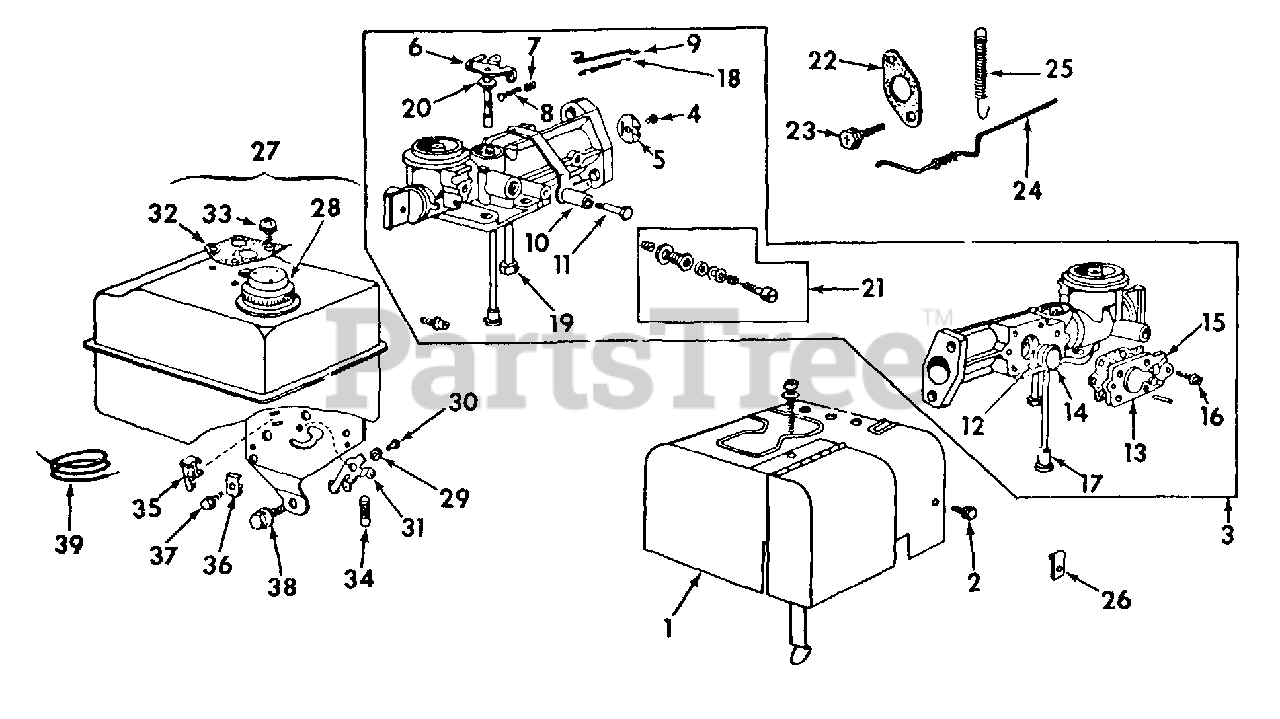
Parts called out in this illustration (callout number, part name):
2	SCREW, NO. 6 X 3/8 SHEET METAL
3	CARBURETOR ASSY
4	SCREW, THROTTLE VALVE
5	VALVE, THROTTLE
6	SHAFT LEVER ASSY, THROTTLE
7	SPRING, THROTTLE ADJUSTING
8	SCREW, THROTTLE ADJUSTING SPRING
9	LINK, THROTTLE
10	BELLCRANK
11	SCREW, SHOULDER
12	SPRING, FUEL PUMP DIAPHRAGM
13	DIAPHRAGM
14	CAP, SPRING
15	COVER, DIAPHRAGM
16	SCREW, DIAPHRAGM COVER
17	SCREEN, FUEL PIPE HOUSING
18	SPRING, THROTTLE LINK
19	FUEL PIPE ASSY
20	WASHER, THROTTLE SHAFT
21	KIT, NEEDLE VALVE
22	GASKET, CARBURETOR
23	SCREW, CARBURETOR MOUNTING
24	ROD, CHOKE EXTENSION
25	SPRING, THROTTLE RETURN
26	CLAMP, CHOKE ROD
27	TANK W/CAP, FUEL
28	CAP, FUEL TANK
29	BUSHING, CONTROL LEVER
30	RIVET, TUBULAR
31	LEVER, GOVERNOR CONTROL
32	GASKET, TANK MOUNTING
33	SCREW, FUEL TANK MOUNTING
34	SPRING, GOVERNOR
35	SWITCH ASSY, STOP
36	CLAMP, CASING
37	SCREW W/LOCKWASHER. HEX-HD
38	SCREW, TANK BRACKET MOUNTING
39	WIRE ASSY, STOP SWITCH
